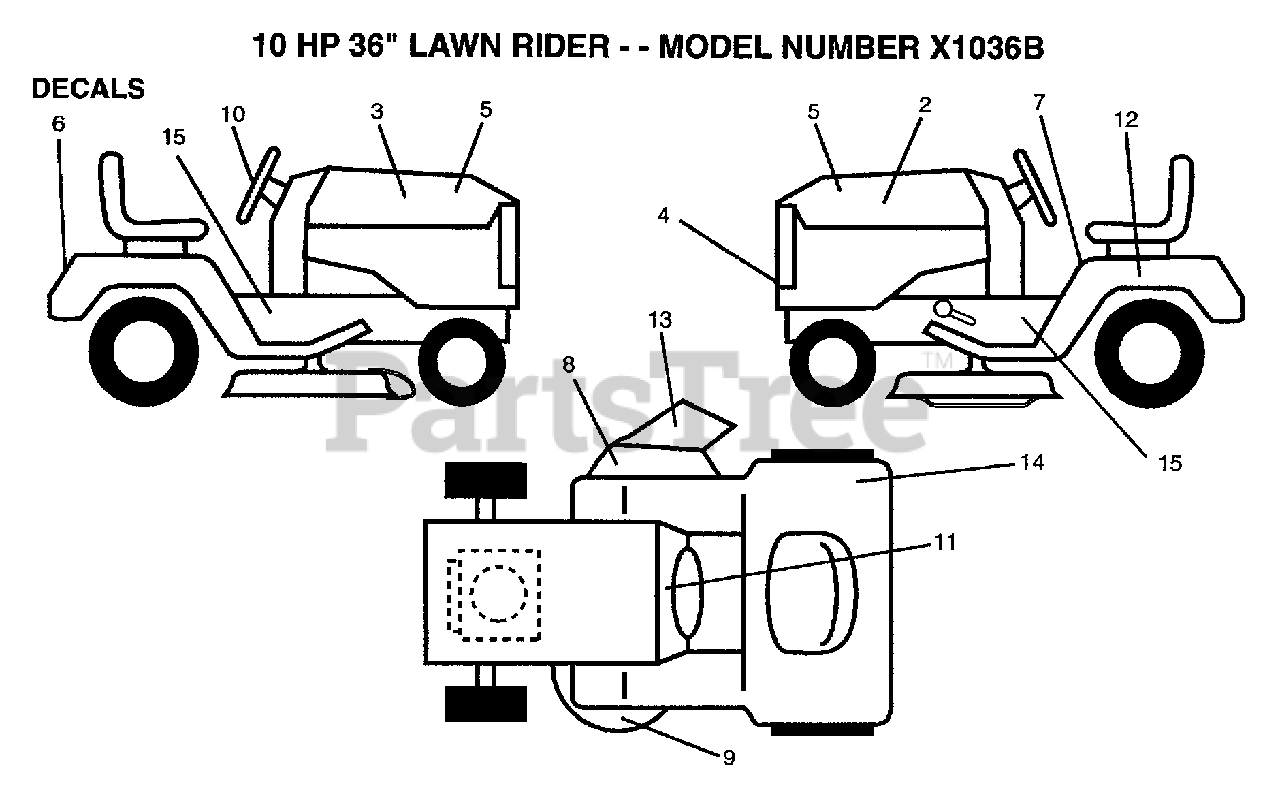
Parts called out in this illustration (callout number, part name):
3	"DECAL,HOOD RH "
4	"DECAL,GRILL "
6	DECAL, FENDER
7	DECAL
8	DECAL WARNING
9	DECAL YT
10	"DECAL,STR WHL "
12	DECAL
13	DECAL WARNING
15	DECAL, CHASSIS
